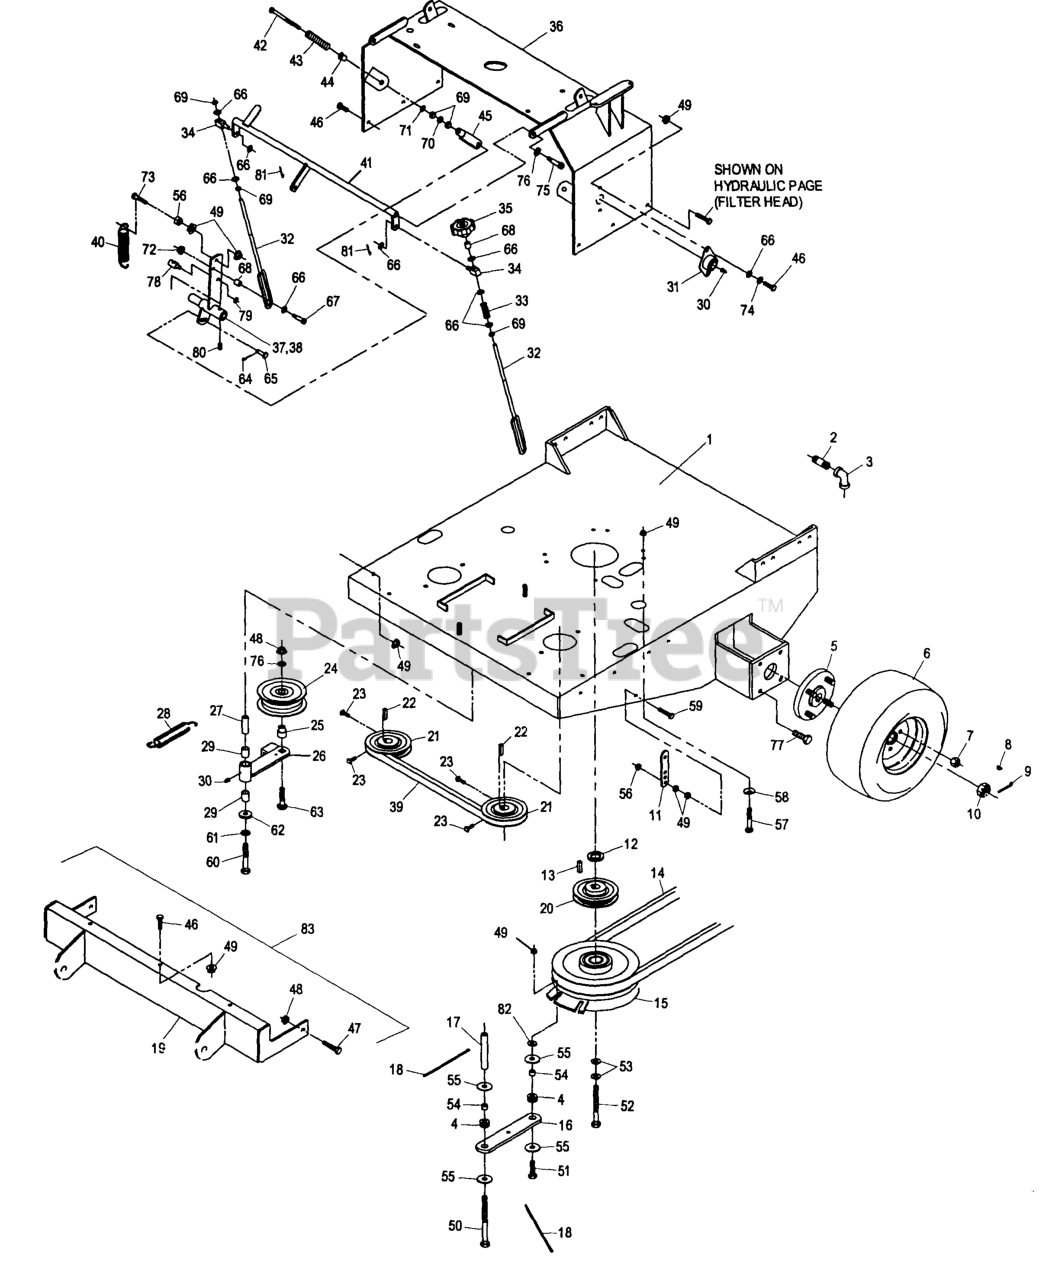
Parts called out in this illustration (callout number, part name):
1	Engine Deck Weldment
2	NIPPLE,PIPE
3	ELBOW-90 DEG
4	GROMMET
8	KEY-WOODRUFF
9	PIN-COTTER
11	TAB-SPRING, EXTENSION
14	BELT,DECK DRIVE
16	STRAP-CLUTCH, BRAKE
17	SPACER-SHIELD
18	TIE-CABLE
19	WLD,SULKY HITCH
21	SHEAVE - PUMP
23	SCREW-SET
25	BUSHING-IDLER
26	IDLER ARM ASM
27	BUSHING
28	SPRING-EXTENSION
29	SLEEVE-BEARING
31	BEARING-FLANGE, SIDE
33	SPRING-COMPRESSION
35	KNOB-TRACKING
39	BELT-HYDRO TRANS DR
40	SPRING-EXTENSION
41	WLD,CRANK SPEED CONTROL
42	BOLT-RETURN, NEUTRAL
43	SPRING-RETURN, NEUTRAL
44	BUSHING-FLANGED
45	YOKE-ADJUSTABLE
53	WASHER-SPRING
58	WASHER-SPRING
59	BOLT-TAP, HH
64	PIN-COTTER
65	PIN-CLEVIS
67	SCREW-HSH
74	WASHER-LOCK
75	SCREW-HSH
80	SCREW-SET
83	Hitch Kit, Sulky
